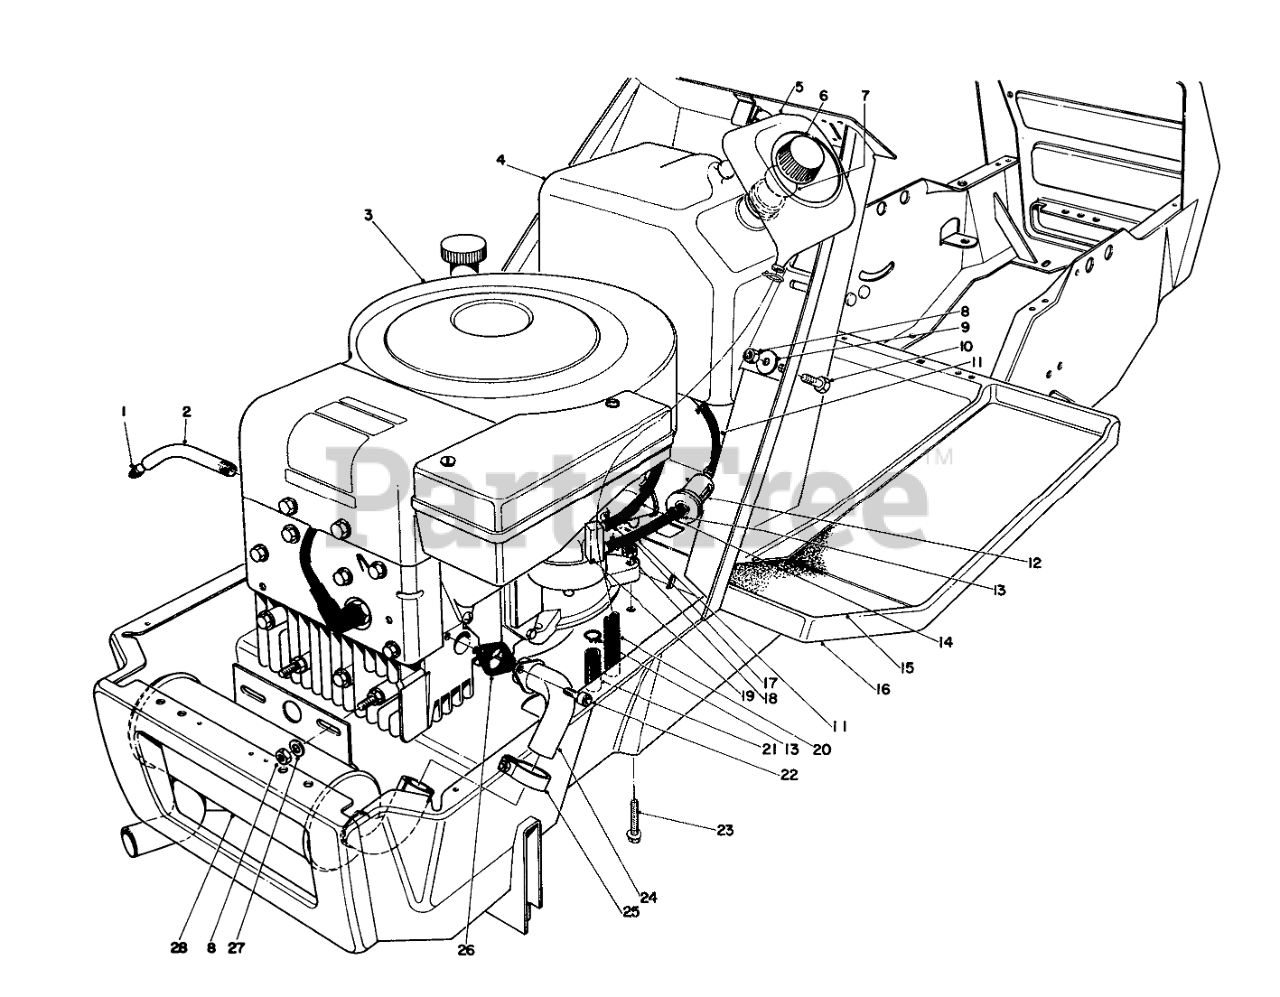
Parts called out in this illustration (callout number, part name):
1	PLUG-PIPE, SQH
2	OIL DRAIN TUBE
3	Engine
4	Gas Tank (Incl. Ref. #5)
5	Funnel Overflow
6	Gas Cap Assembly (Incl. Ref. #7)
7	Gasket Gas Cap
8	NUT-LOCK, CONE
9	WASHER
10	SCREW-HH
11	GAS HOSE
12	Fuel Filter
13	HOSE CLAMP
14	Gas Return Hose
15	LH FOOT TREAD
16	Frame
17	Clamp
18	NUT-LOCK, CONE
19	Fitting Carburetor
20	Hose Funnel
21	Hose Carburetor Drain
22	SCREW-HSH
23	SCREW-HH
24	10 HP EXHAUST PIPE WA
25	MUFFLER CLAMP
26	Gasket Exhaust
27	WASHER-PLAIN
28	EXHAUST MUFFLER 10 HP
